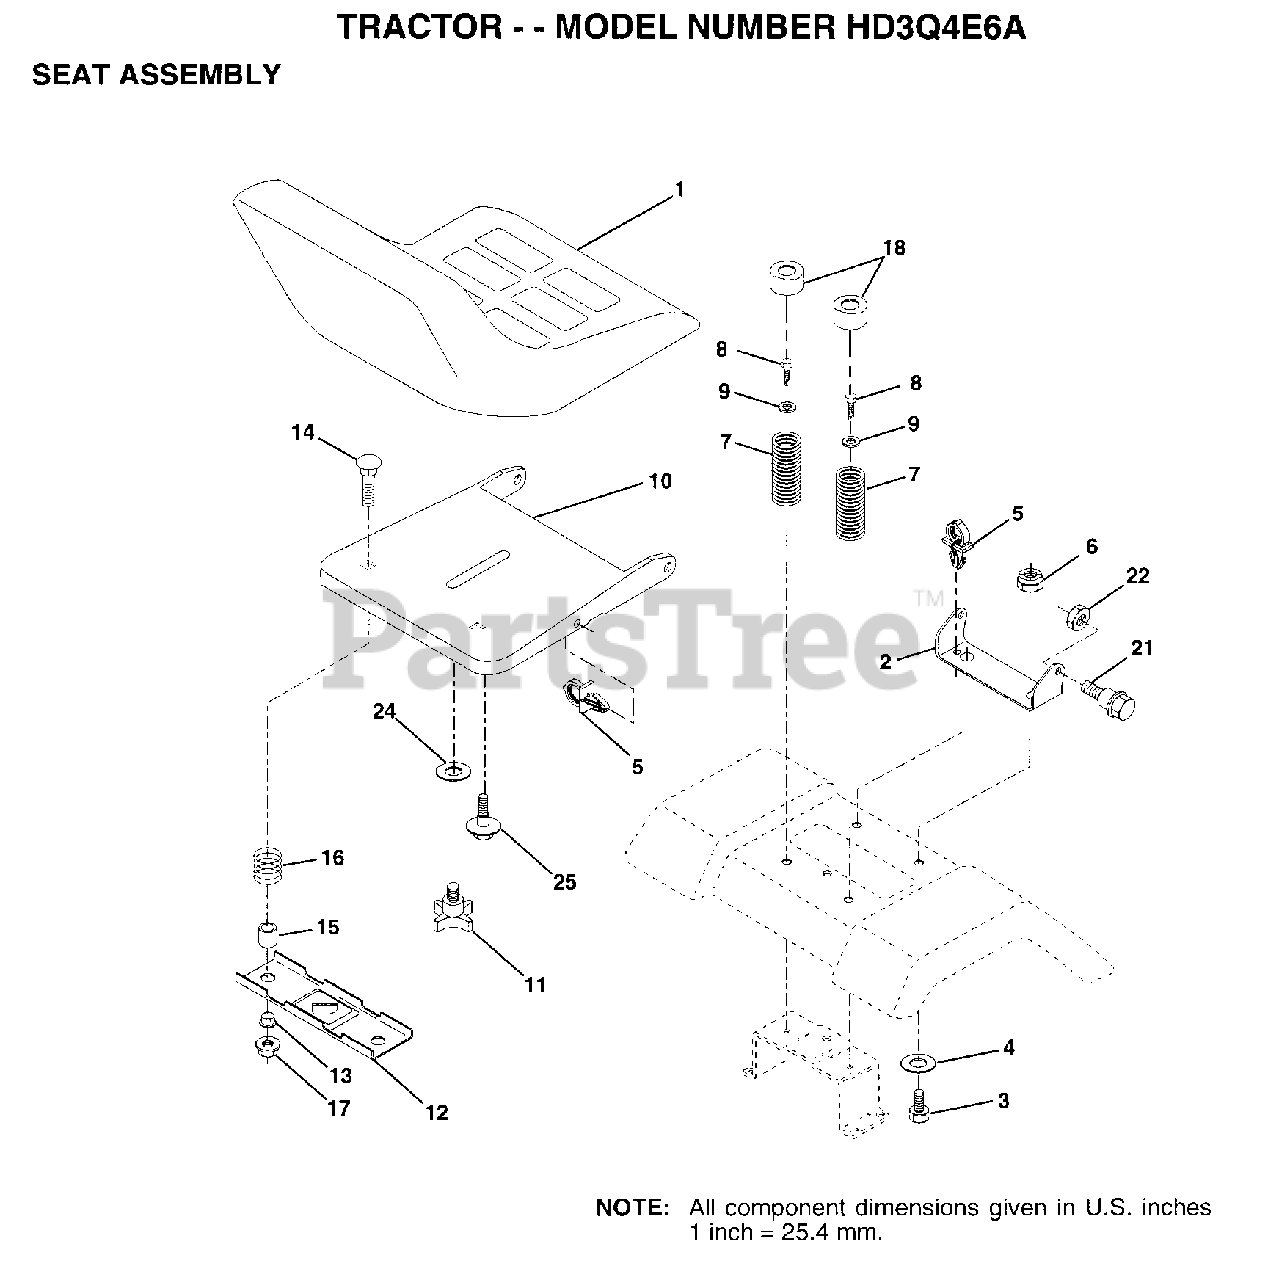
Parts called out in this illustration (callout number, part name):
1	SEAT.2500/1516.BK
2	BRACKET PVT SEAT
3	BOLT
4	WASHER PM
5	CLIP.PUSH-IN.HING
6	NUT
7	SPRING COMPRESSIO
8	SCREW GTV
9	WASHER
11	"KNOB 1/2"" YT"
12	BRKT SWITCH
13	BUSHING
15	SPACER SPLIT
16	SPRING COMPRESSED
18	CAP SPRING
21	BOLT.SHLD.5/16-18
22	NUT
24	WASHER
25	"BOLT,SHOULDER"
